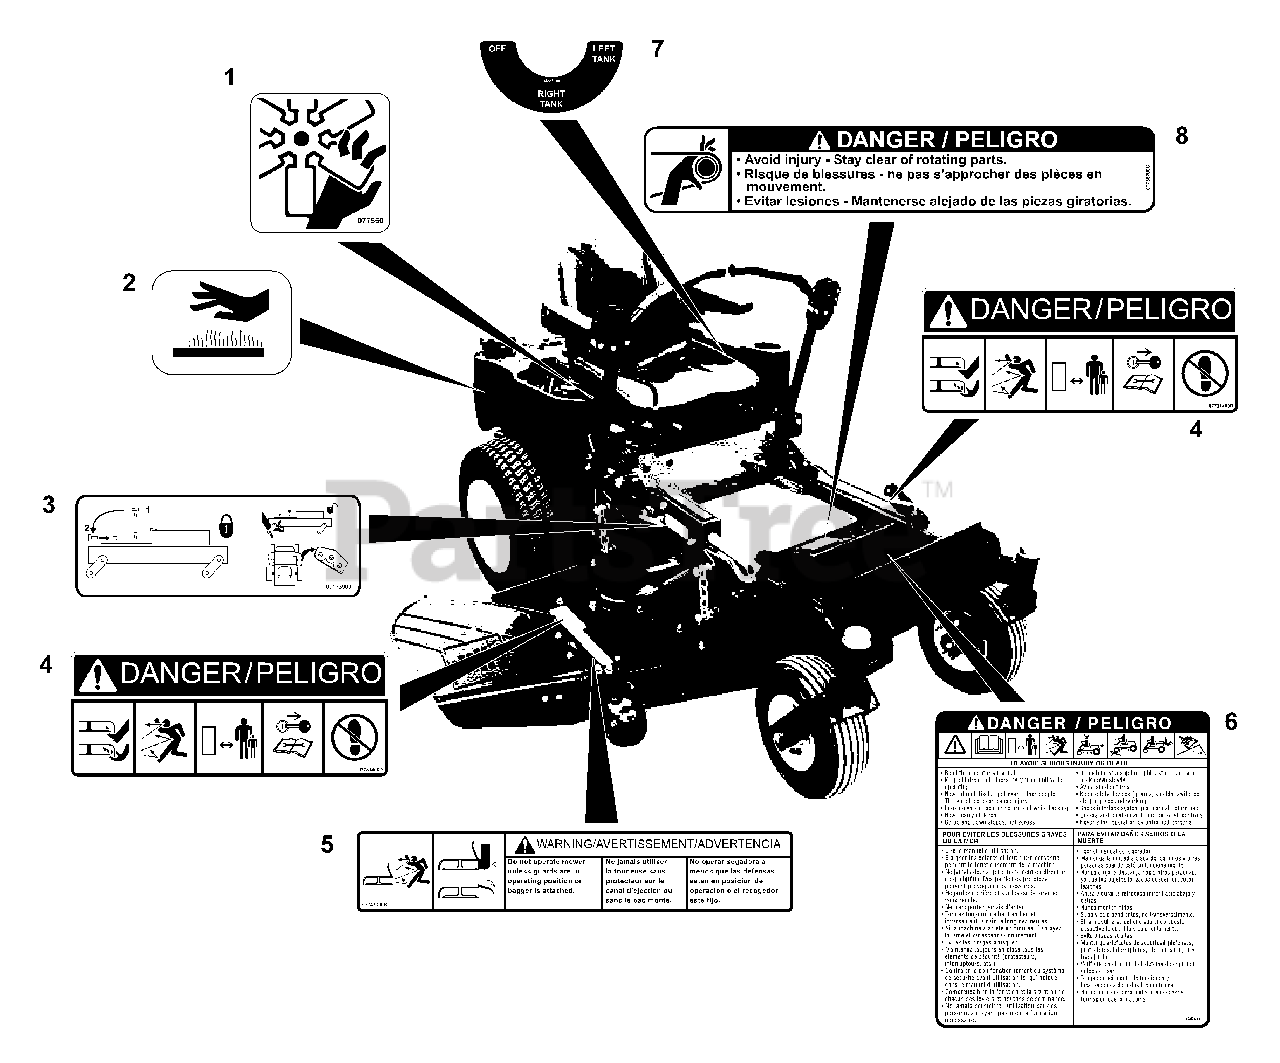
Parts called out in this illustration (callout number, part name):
1	Decal, Danger Fan
2	Decal, Hot Surface
3	Decal, Deck Service
4	Decal, Mower Pan Head Danger
5	Decal, Warning
6	Set, Decal Common Danger/Fuel
7	Decal, Fuel Valve
8	Decal, Danger
